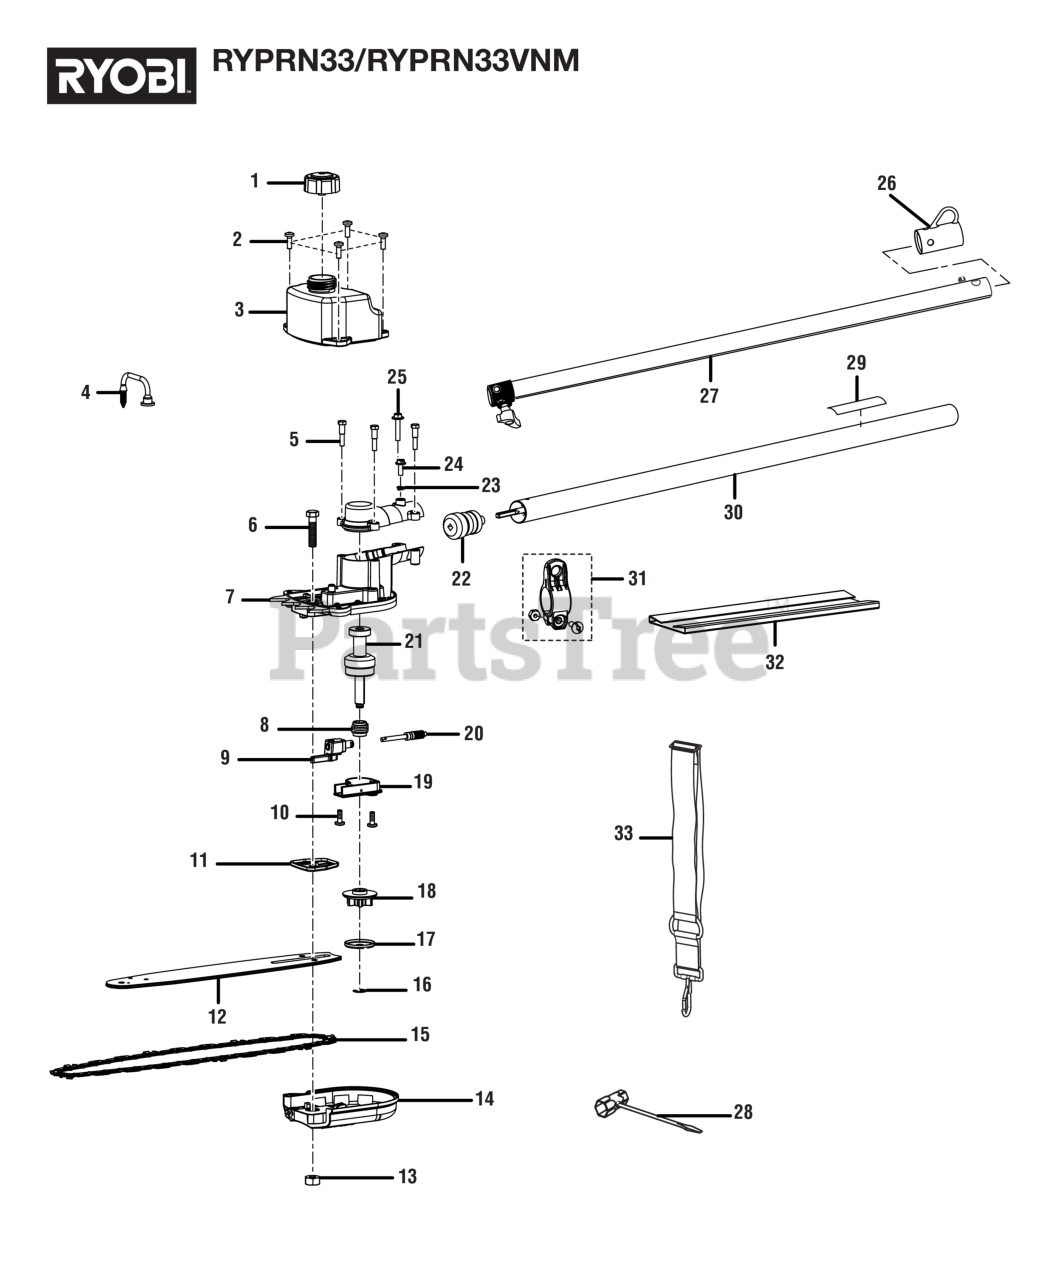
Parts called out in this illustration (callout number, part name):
1	Oil Cap Assembly
2	Screw (M5 x 18 mm)
3	Oil Tank Cover Assembly
4	Oil Pickup Tube
5	Screw (M5 x 25 mm, Shoulder Screw)
6	Screw (M8 x 35 mm)
7	Gear Case Assembly
8	Worm Gear
9	Oil Pump Seal Assembly
10	Screw (M5 x 13 mm)
11	Bar Pad Plate
12	Guide Bar
13	Hex Nut (M8 x 1.25, Special)
14	Bar Clamp Assembly
15	Chain (10 in.)
16	E-Ring (Dia. 6 mm)
17	Cupped Washer
18	Sprocket
19	Oil Pump Housing w/Cam Pin Assembly
20	Pinion Gear and Plunger Assembly
21	Output Shaft Assembly
22	Pinion and Bearing Assembly
23	Spring Washer (M5)
24	Screw (M5 x 15 mm)
25	Screw (M5 x 25 mm)
26	Storage Hanger Cap
27	Intermediate Boom Assembly
28	WRENCH - COMBINATION
29	Warning Label
30	Lower Drive Shaft Assembly
31	Strap Hanger
33	Shoulder Harness Assembly
